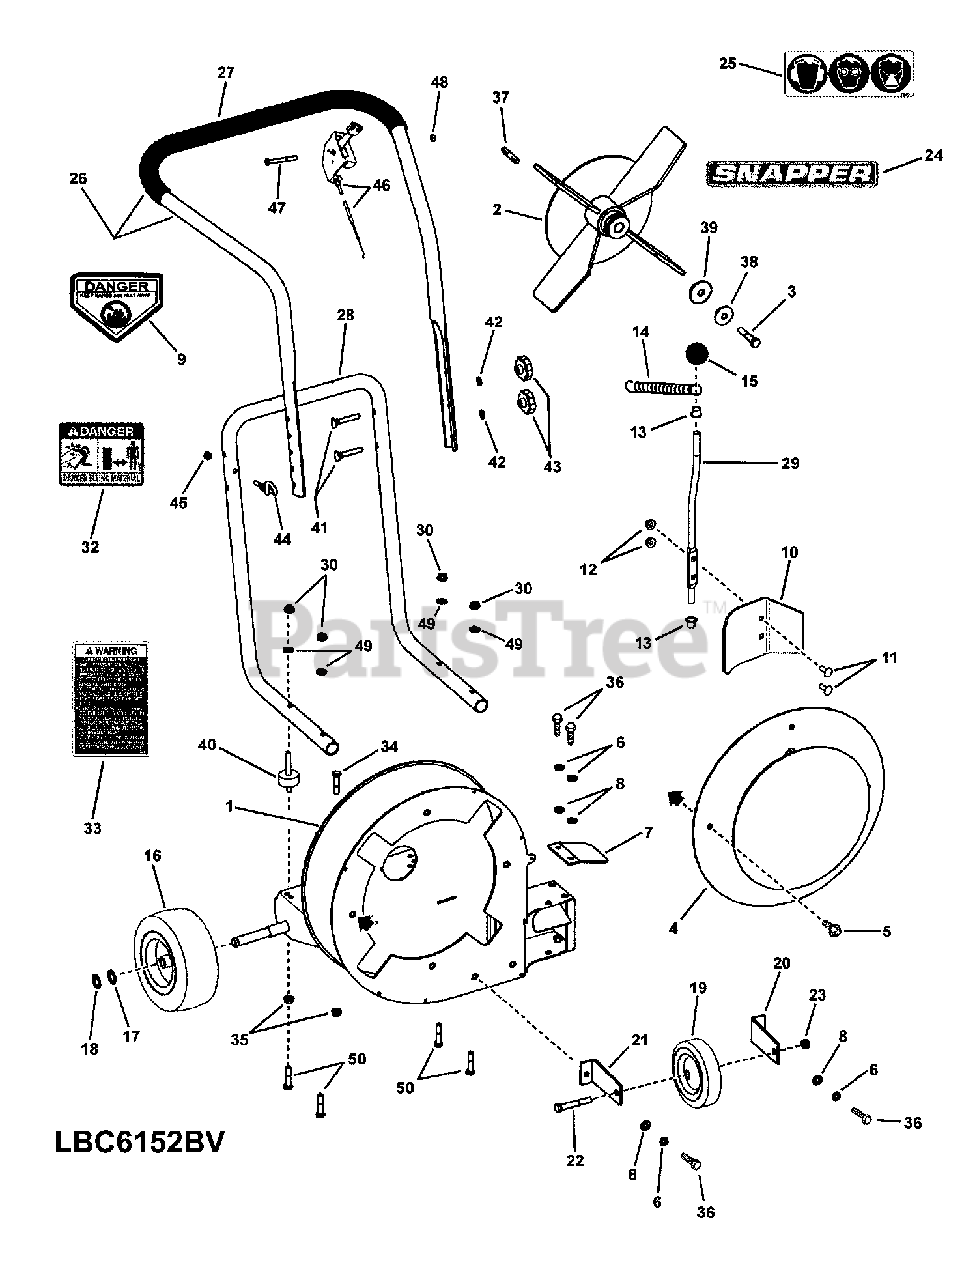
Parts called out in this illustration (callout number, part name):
1	WELDMENT, Base & Housing, 52 Classic
2	WELDMENT, Steel Impeller, 4 Blade, 15.00 O.D.
3	SCREW, 3/8-24 x 2" Hex Head Cap, GR 5
4	WELDMENT, Intake Baffle
5	BOLT, 5/16-18 x 1/2" Hex Flange Lock
6	WASHER, 5/16" Split
7	DEFLECTOR, Side Air
8	WASHER, .34 x .69 x .08 Flat
9	DECAL, Danger, Cut Finger (CPSC)
10	DOOR, Forward Air Control
11	BOLT, 1/4-20 x 3/4" Short Square Neck, GR 5
12	NUT, 1/4-20 Hex Flange Lock, GR 5
13	BEARING, 3/8 Clip
14	SPRING, Extension
15	KNOB, #230 Dimco (3/8-16 thread)
16	*ASSEMBLY, Wheel & Tire, Sawtooth 4.10/3.50-4 Kenda
17	WASHER, .64 x .99 x .05 Flat
18	RING, External Retaining
19	WHEEL, 6.00 x 1.50 Semi-Pneumatic
20	BRACKET, Caster- RH
21	BRACKET, Caster- LH
22	SCREW, 3/8-16 x 2-1/2" Hex Head Cap, GR 5
23	NUT, 3/8-16 Hex Center Lock, GR 5 or B
24	DECAL, SNAPPER
25	DECAL, Personal Protection
26	ASSEMBLY, Upper Handle & Grip- Narrow
27	GRIP, 1.0 x 21-1/2" Foam
28	HANDLE, Lower Folding, Narrow, Blower
29	ROD, Door Front/Side Discharge
30	NUT, 5/16-18 Hex Nyloc
32	DECAL, Danger, Flying Material
33	DECAL, Leaf Blower Warning
34	SCREW, 5/16-18 x 1-1/2" Hex Head Cap, GR 5
35	NUT, 5/16-18 Hex Flange Lock, GR 5
36	SCREW, 5/16-18 x 3/4" Hex Head Cap, GR 5
37	KEY, 1/4" Square x 2"
38	WASHER, .411/.406 I.D. Cone
39	WASHER, .468 x 1.625 x .25 Flat
40	MOUNT, Vibration (5/16-18 threads, both ends)
41	BOLT, 5/16-18 x 2" Curved Head Square Neck, GR 2
42	WASHER, 5/16" Internal Tooth Lock
43	KNOB, Folding Handle
44	ROPE GUIDE (1/4-20 thread)
45	NUT, 1/4-20 Hex Center Lock, GR 5 or B
46	THROTTLE CONTROL, B&S, 35.00/1.62
47	SCREW, 1/4-20 x 2" Hex Head Cap, GR 5
48	NUT, 1/4-20 Hex Nyloc
49	WASHER, 5/16" Curved
50	SCREW, 5/16-18 x 1-3/4" Hex Head Cap, GR 5
